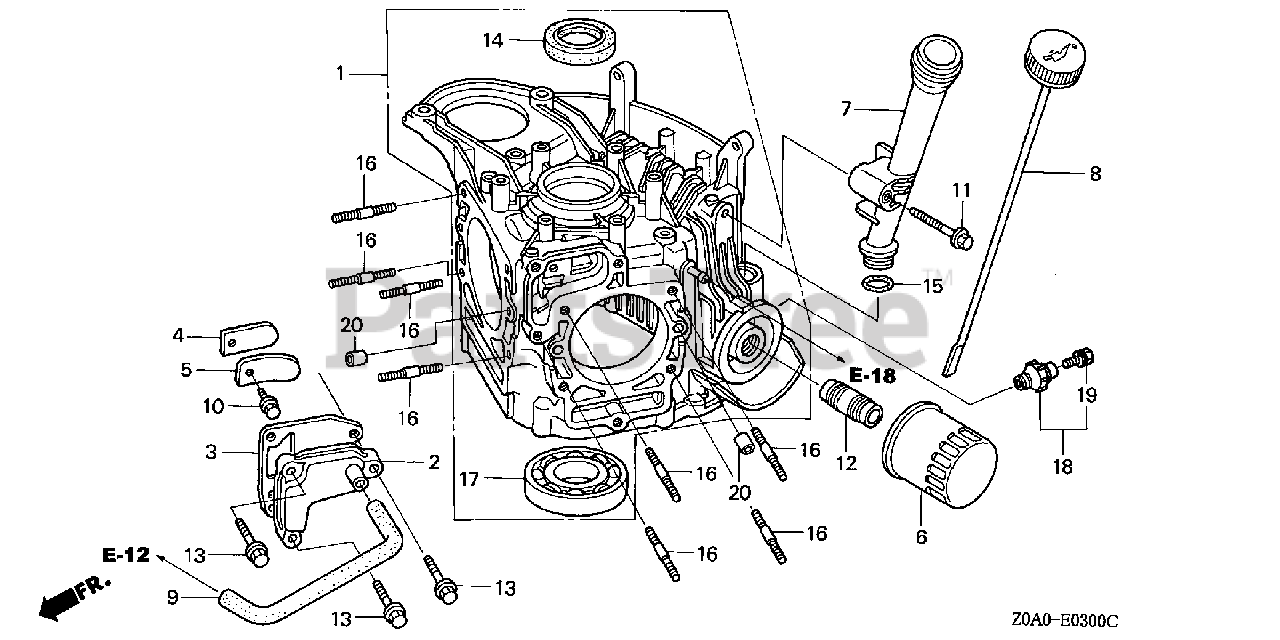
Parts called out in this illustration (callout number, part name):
1	CRANKCASE ASSY. (810)
2	COVER, BREATHER
3	GASKET, BREATHER COVER
4	PLATE, VALVE
5	STOPPER, VALVE
6	FILTER, OIL
7	EXTENSION, OIL FILLER
8	DIPSTICK, OIL
9	TUBE, BREATHER
10	BOLT, FLANGE (5X10)
11	BOLT, FLANGE (6X45)
12	HOLDER, OIL FILTER
13	BOLT, FLANGE (6X25)
14	OIL SEAL (35X52X8)
15	O-RING (22.5X2.2)
16	BOLT 2, STUD (8X28)
17	BEARING, RADIAL BALL (6207)
20	PIN A, DOWEL (8X14)
